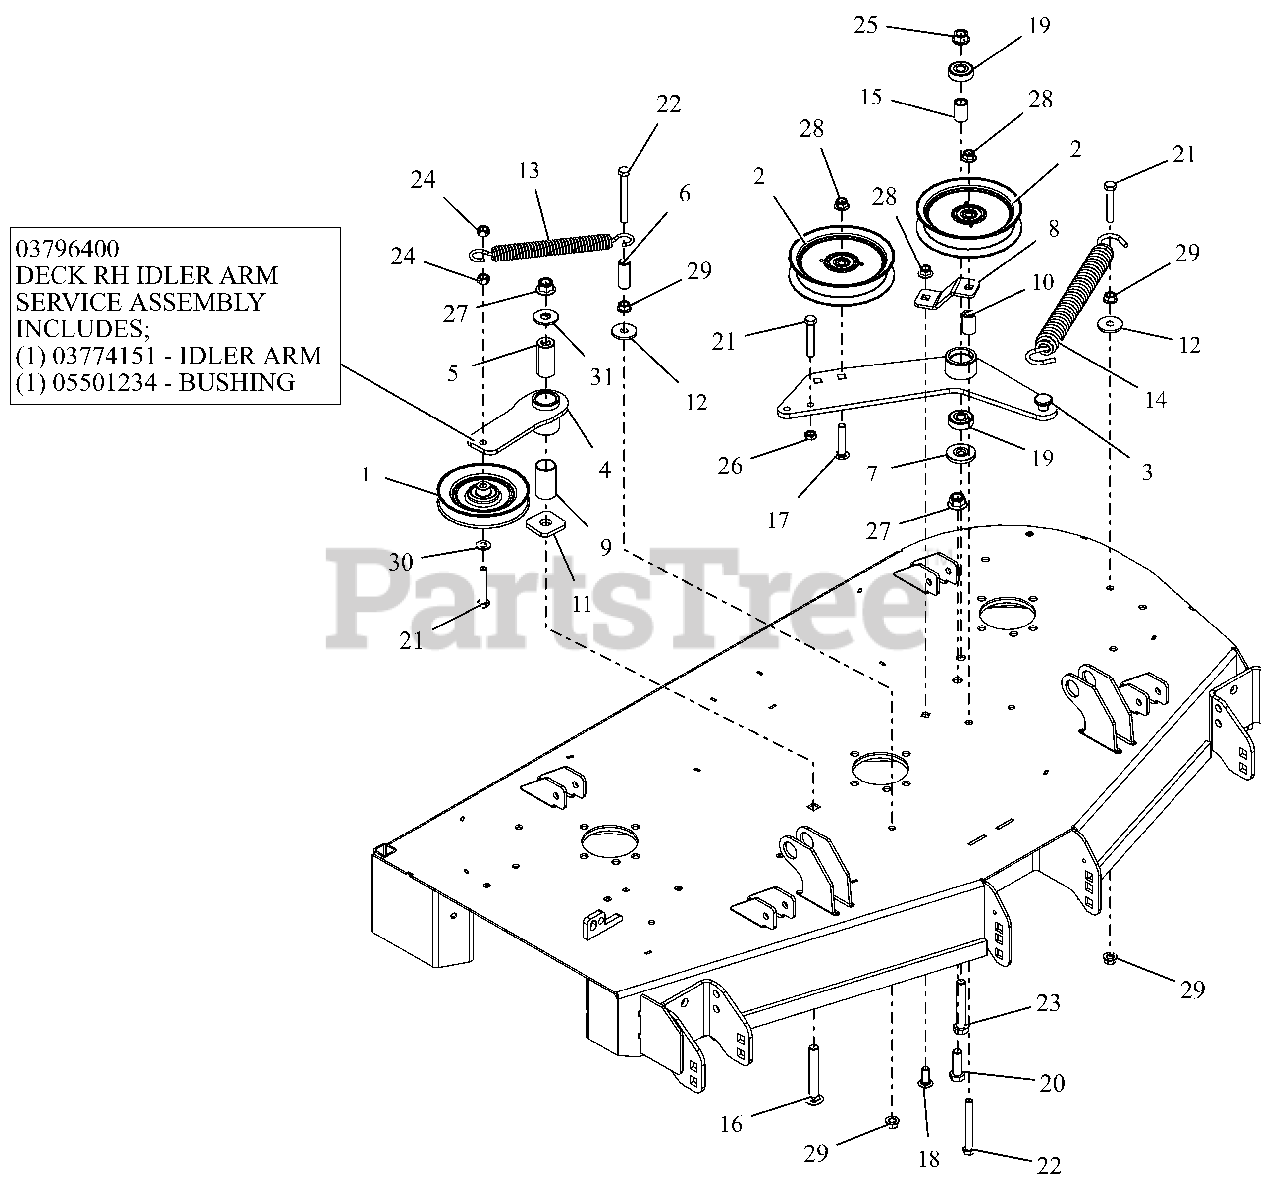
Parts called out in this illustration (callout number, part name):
1	IDLER, V-5.00"
2	IDLER, FLAT 5.00"
3	DECK PTO IDLER ARM WLDMT - BLK
4	WMT, IDLER ARM - BLACK
4	ASM, IDLER ARM (DECK)
4	BSHG, 1.00X1.125X1.937
5	BSHG, SPCR .502X.997X2.03 PM
6	SPACER, .375IDX.625ODX1.66 PM
7	SPACER, IDLER ARM
8	PTO FIXED IDLER MTG BRKT -RED
9	BSHG, 1.00X1.125X1.937
10	BUSHING, SLV .380X.750X1.190
11	WSHR-FLT .640X1.75X.250
12	WSHR-FL-STL .406X1.375X.135 YZ
13	SPRING, EXTENSION
14	SPRING, EXTENSION
15	SPACER .510 X .75 X 1.1485
16	@BLT-RDHDSQNK .50-13X3.50 G5YZ
17	BLT-RDHDSQNK .38-16X2.00 SHTYW
18	@BLT-RDHDSHSQNK.38-16X1.0 G5YZ
19	BRG-BALL .500X1.38X.437
20	@BLT-HEX .50-13X1.50 GR5 YWZC
21	@BLT-HEX .38-16X2.25 GR5 YWZC
22	@BLT-HEX .38-16X3.25 GR5 YWZC
23	@BLT-HEX .50-13X3.00 GR5 YWZC
24	@NUT-LK-CTR .38-16 YWZC
25	NUT-LK-CTR-FLG .50-13 YWZC
26	NUT-HEX-JAM .375-16 YWZC
27	@NUT-LK-NYL-FLG .50-13 YWZC
28	@NUT-LK-NYL-FLG .38-16 YWZC
29	@NUT-SPNLK-FLG .375-16 YWZC
30	@WSHR-FL-STL.406X.812X.065 YWZ
31	@WSHR-FL-STL.563X1.38X.109YWZC
